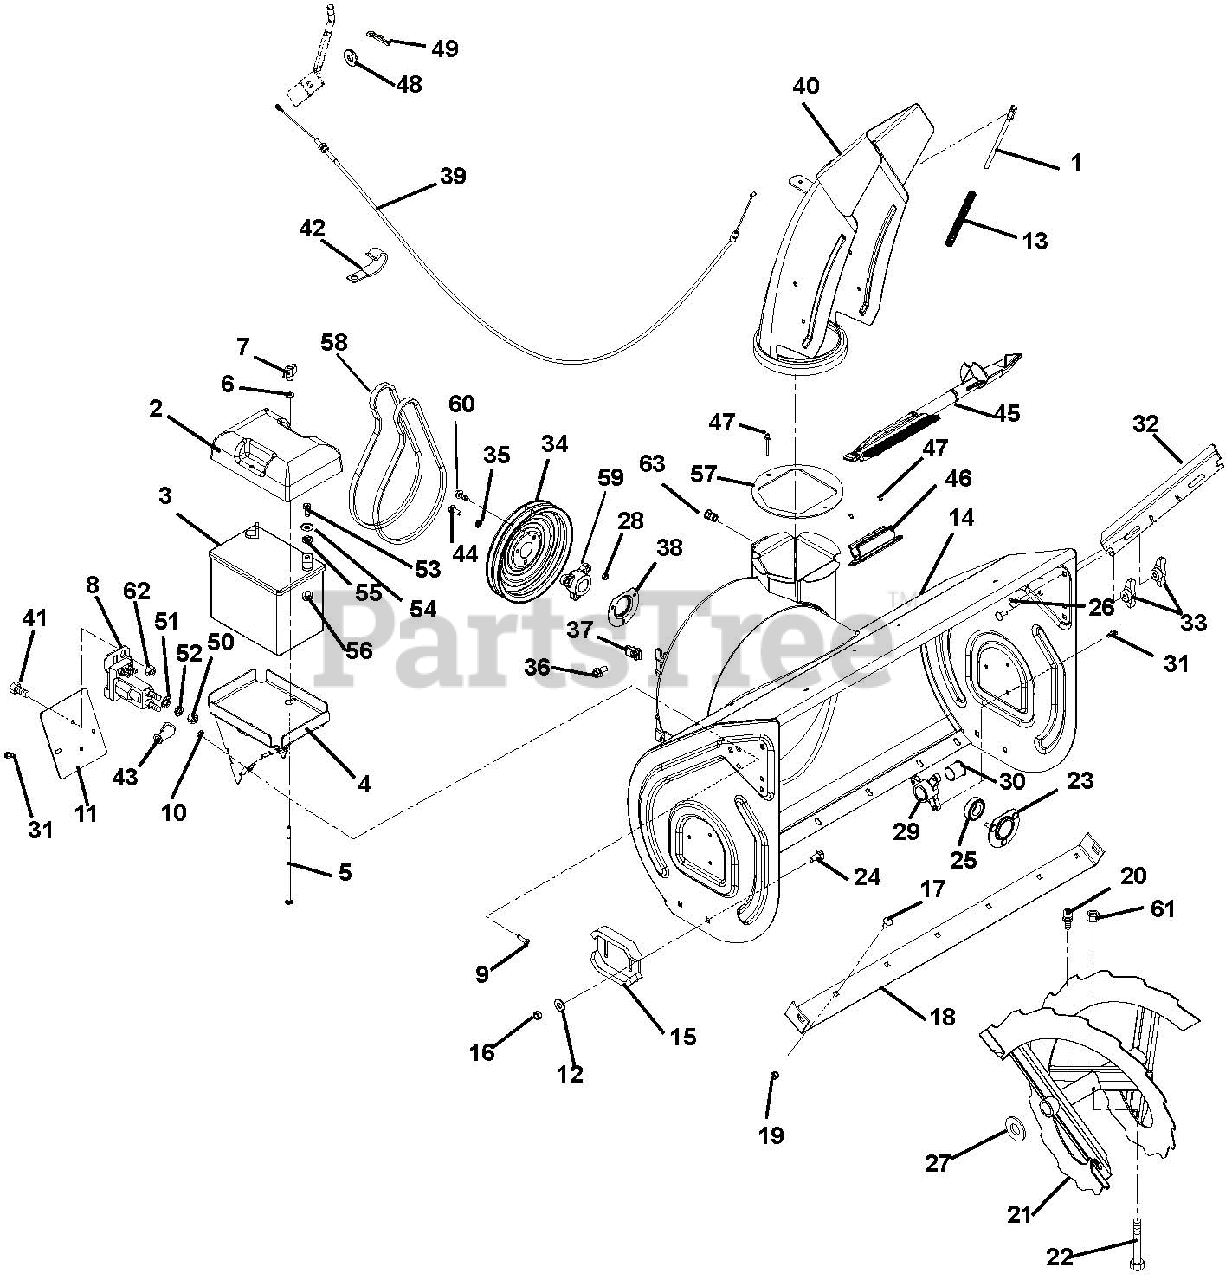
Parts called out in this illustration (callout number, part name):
1	ROD, DEFLECTOR CAP
2	COVER, BATTERY
4	TRAY, BATTERY-W/CLIPS
5	@BLT-RDHDSQNK .25-20X7.00 G2YZ
6	@WSHR-FL-STL.281X.62X.065 YWZC
7	KNOB, WING - .25-20 UNC
8	SOLENOID
9	BLT-HEX .25-20X.75 HWH YZ GR5
10	NUT-RTNR .25-20X.56
11	COVER, SOLENOID
12	@WSHR-FL-STL.438X1.00X.083 YWZ
13	SG-COMP .08X.40X6.50 14#/IN
14	BL0WER HOUSING W/DECAL 26"
14	BLOWER HOUSING W/DECAL 28"
14	BLOWER HOUSING W/DECAL 32"
14	BLOWER HOUSING W/DECAL 32" BAT
14	BLOWER HOUSING W/DECAL 36"
14	BLOWER HOUSING W/DECAL 36" BAT
15	RUNNER, SKID SHOE
16	@NUT-LK-CTR .38-16 YWZC
17	BLT,RDSHHDSQSHNK .31-18X.62 YZ
18	BLADE, SCRAPER-26"
18	BLADE, SCRAPER-28"
18	BLADE, SCRAPER-32"
18	BLADE, SCRAPER-36"
19	@NUT-LK-TOP-FLG .31-18 YWZC
20	ZERK,FITTING .25X.125 DRIVE IN
21	RAKE, LH-26"(1 ID X 15.75 OD)
21	RAKE, RH-26"(1 ID X 15.75 OD)
21	RAKE, LH-28"(1 ID X 15.75 OD)
21	RAKE, RH-28"(1 ID X 15.75 OD)
21	RAKE, LH-32"(1 ID X 15.75 OD)
21	RAKE, RH-32"(1 ID X 15.75 OD)
21	RAKE, LH-36" (1 ID X 15.75 OD)
21	RAKE, RH-36"(1 ID X 15.75 OD)
22	SHEAR BOLT SERVICE ASSEMBLY
23	BEARING FLANGE
24	@BLT-RDHDSHSQNK.38-16X1.0 G5YZ
25	BRG-BALL .876X1.75X.50 RSTFP
26	@BLT-RHDSSQNK .31-18X.75 G5YZ
27	WSHR-FL-STL 1.010X1.505X.062YZ
28	@NUT-LK-CTR .25-20 YWZC
29	BUSHING, RAKE SHAFT 1"
30	BSHG-FLG, SPLIT NYLINER 1.0"ID
31	SCR-TAP .25-20X.50 HWH TR YWZ
32	CUTTER, DRIFT
33	KNOB,WING .31-18 UNC NYL/TALC
34	PULLEY, SPIN FORM DUAL GROOVE
35	WSHR-LK .312X.097 HVY YWZC
36	BLT-SERHFWH .38-16X.75 YWZC
37	NUT-RTNR .375-16X.37
38	BEARING FLANGE
39	CABLE, DEFLECTOR-COATED
40	CHUTE, DISCHARGE-W/DEFLECTOR
41	@BLT-HEX .25-20X.50 GR5 YWZC
42	J-CLAMP
43	BOOT, EYELET TERMINAL
44	BLT-HEX .31-24X.75 YWZC GR5
45	DEVICE, SNOW CLEAN OUT W/BRUSH
46	MOUNT, SNOW CLEAN OUT
47	RVT-POP .187 YZ
48	@WSHR-FL-STL.281X.62X.065 YWZC
49	PIN-HAIR INT .06X.18X.77
50	NUT-JAM .31-24 YWZC
51	WSHR-LOCK INT .31 YWZC
52	@WSHR-LK .31X.078 REG YWZC
53	@BLT-HEX .25-20X.75 GR5 YWZC
54	WSHR-FL-STL .265X.50X.087YWZC
55	@WSHR-LK .25X.062 REG YWZC
56	@NUT-HEX .25-20 YWZC
57	BAFFLE, DISCHARGE NECK
58	V-BELT, HA-RAW EDGE (SET)
59	PULLEY HUB, D-BORE .87 PRO
60	@SCR-TAP .31-18X.50 HWH TR YWZ
61	@NUT-LK-CTR .31-18 YWZC
62	@NUT-LK-CTR .25-20 YWZC
63	NUT, THREADED INSERT .38-16
